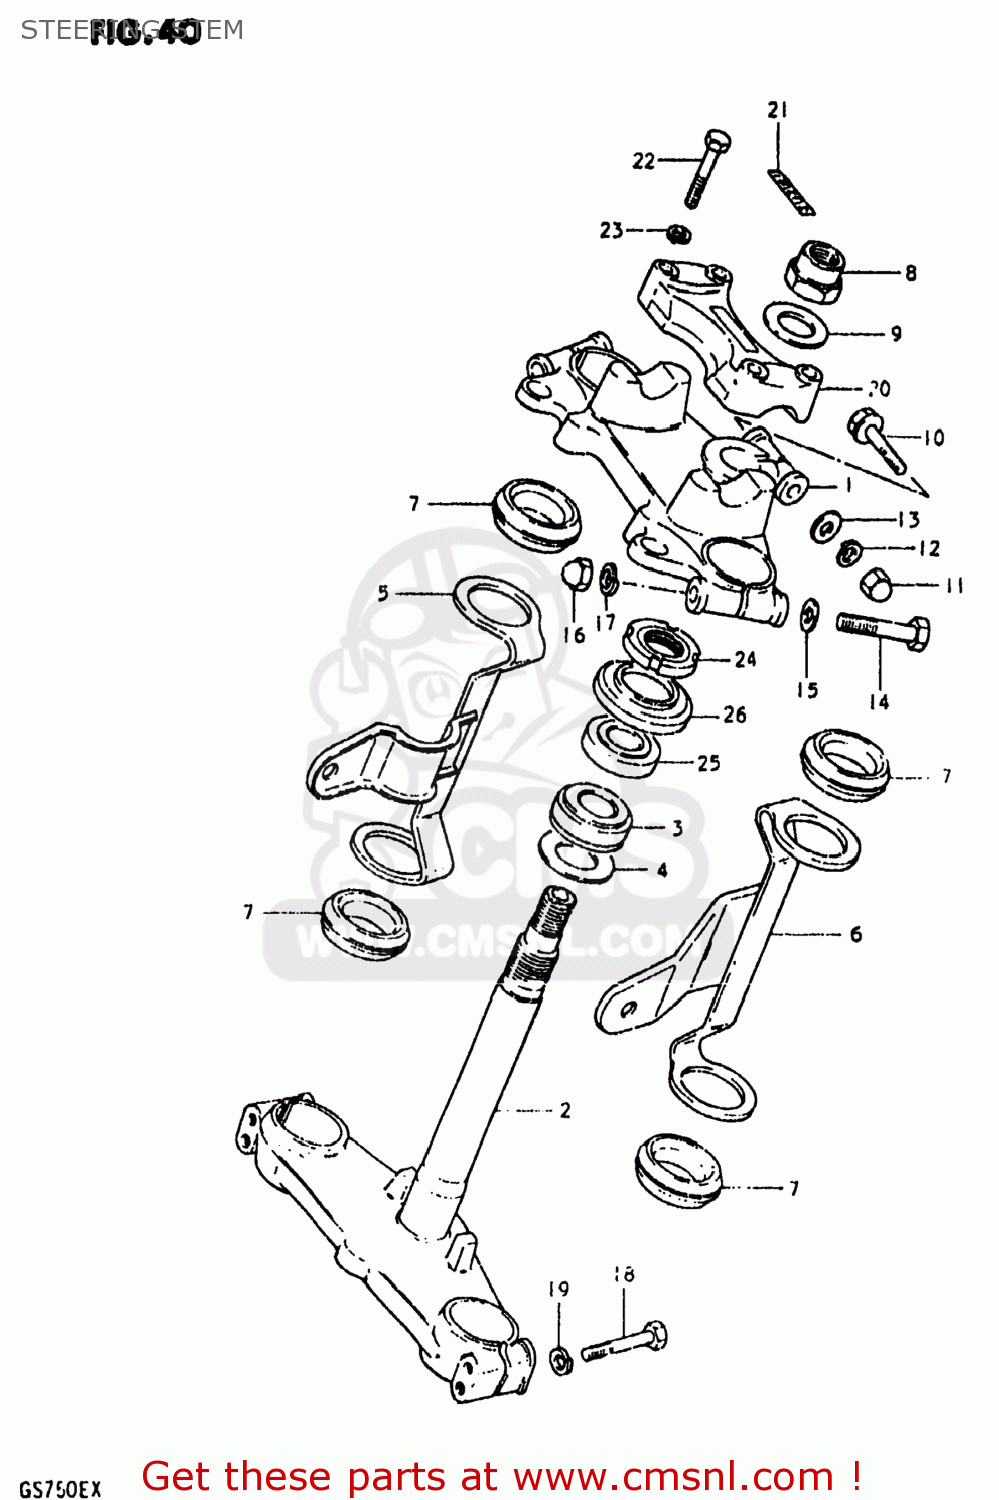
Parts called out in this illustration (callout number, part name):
1	HEAD,STEERING STEM
2	STEM,STEERING
3	BEARING
4	WASHER,THRUST
5	BRACKET,HEADLAMP,RIGHT
6	BRACKET,HEADLAMP,LEFT
7	CUSHION,HEADLAMP BRACKET
8	NUT,FR FORK UPR BRACKET
9	WASHER
10	BOLT
11	NUT,M8X1.25X12
12	LOCK WASHER
13	WASHER
14	BOLT 10X55
15	WASHER
16	NUT
17	LOCK WASHER
18	BOLT 8X45
19	WASHER,LOCK,8.
20	HOLDER,HANDLEBAR
21	EMBLEM,HANDLE CLAMP
22	BOLT
23	LOCK WASHER
24	NUT,STEERING STEM(25X44X10)
25	TAPER,ROLLER BEARING
26	DUST SEAL,STEERING,UPPER
